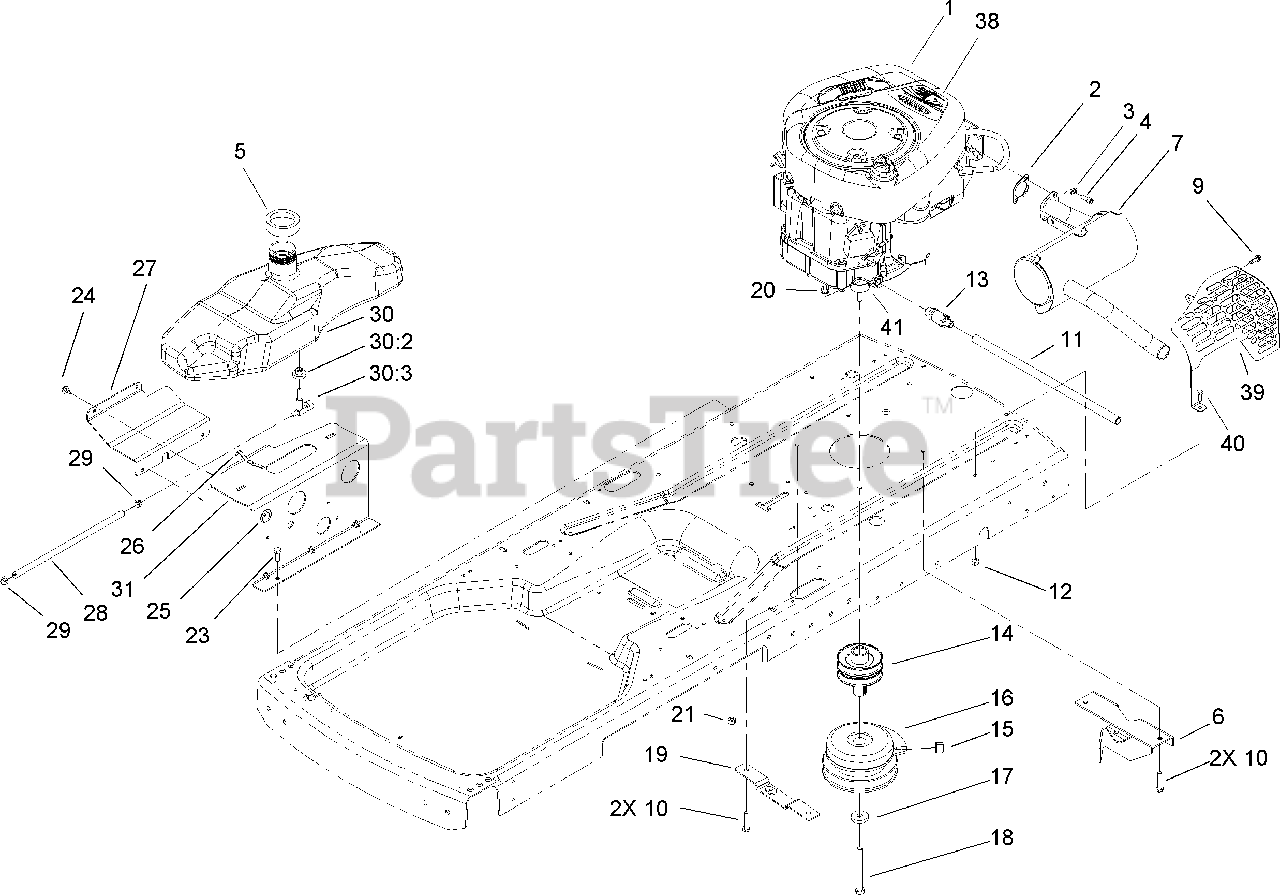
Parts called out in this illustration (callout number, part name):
2	GASKET-MUFFLER
3	WASHER-LOCK
4	SCREW-HSH
5	SEAL-FOAM
6	BRACKET-PIVOT
9	SCREW-HWH
10	SCREW-HH
11	TUBE-DRAIN, OIL
12	NUT-LOCK, NI
13	VALVE-DRAIN, OIL
14	PULLEY-ENGINE
16	CLUTCH-ELECTRIC
18	SCREW-HH
19	PLATE-MOUNT, IDLER
21	NUT-LOCK, NI
23	SCREW-HH
24	SCREW-HHF
27	PLATE-SUPPORT
28	HOSE-FUEL
30	FUEL TANK ASM
30:3	VALVE-FUEL
38	DECAL-ENGINE
39	GUARD-MUFFLER
40	SCREW-HH
41	REDUCER-THROTTLE, RPM
